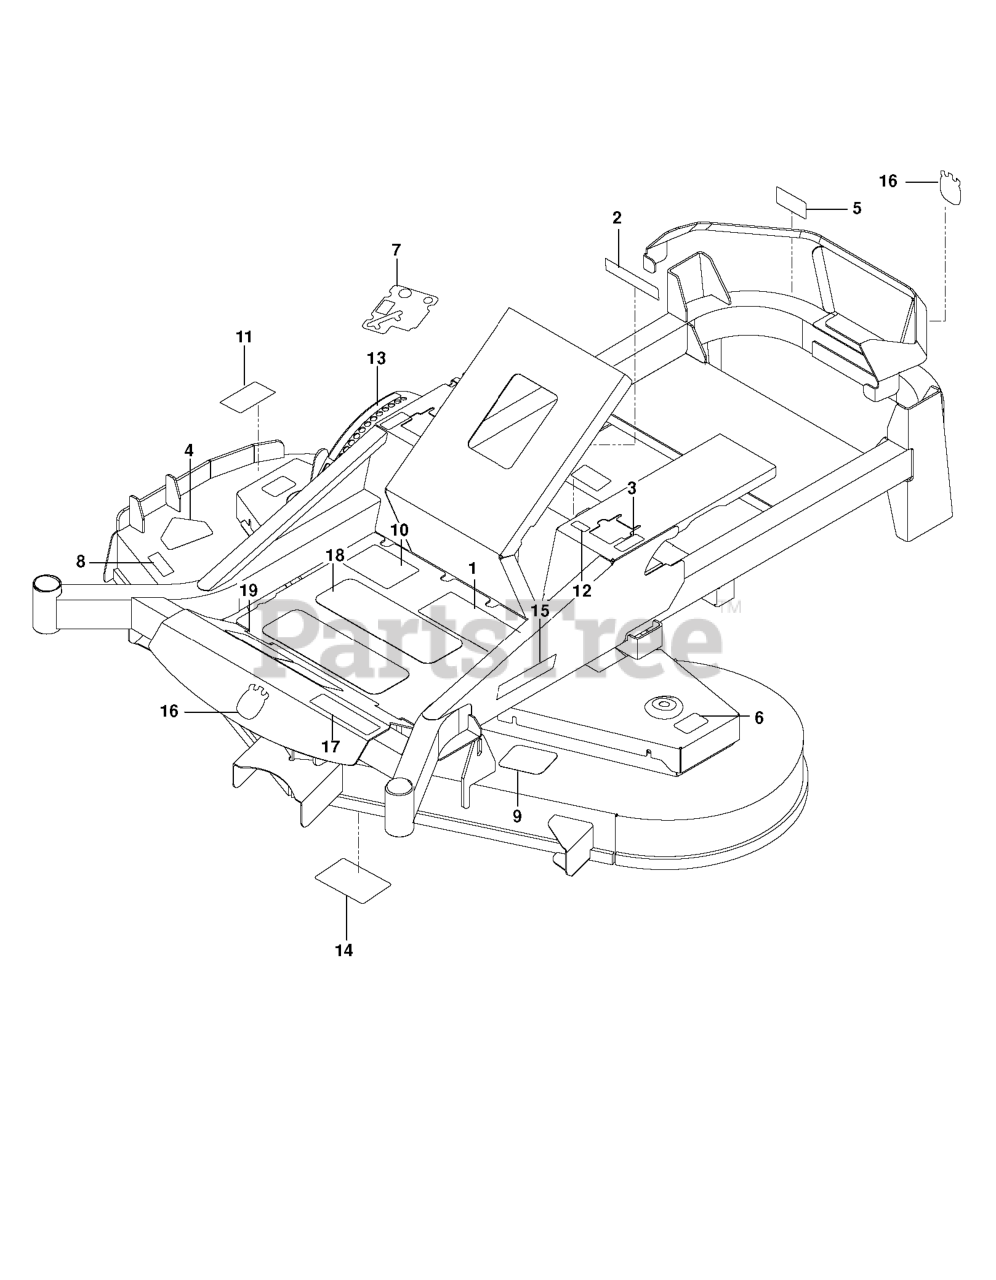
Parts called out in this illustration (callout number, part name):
1	DECAL, WARNING
2	EURO DECAL-BATTERY WARNIN6
3	DECAL, MOTION CONTROL
4	DECAL, CPSC
5	DECAL, BELT DRIVE
6	DECAL.DECK.6MIL.EURO.NOSTEP
7	DECAL, CONSOLE HUS
8	DECAL, EURO SEVERING
9	DECAL, BELT ROUTING
10	DECAL, WARNING
11	DECAL.DECK.6MIL./DEF.SHLD.WARN
12	DECAL, F.S.T.
13	DECAL, HEIGHT ADJUST
14	DECAL, SERVICE
15	RP.DECAL.BADGE.170MM.TEXTLOGO
16	DECAL.AUGER.HUSQ.CROWN.SNOW
17	DECAL.ZTR.MZ61.HUSQ
18	ANTI-SKID PAD
